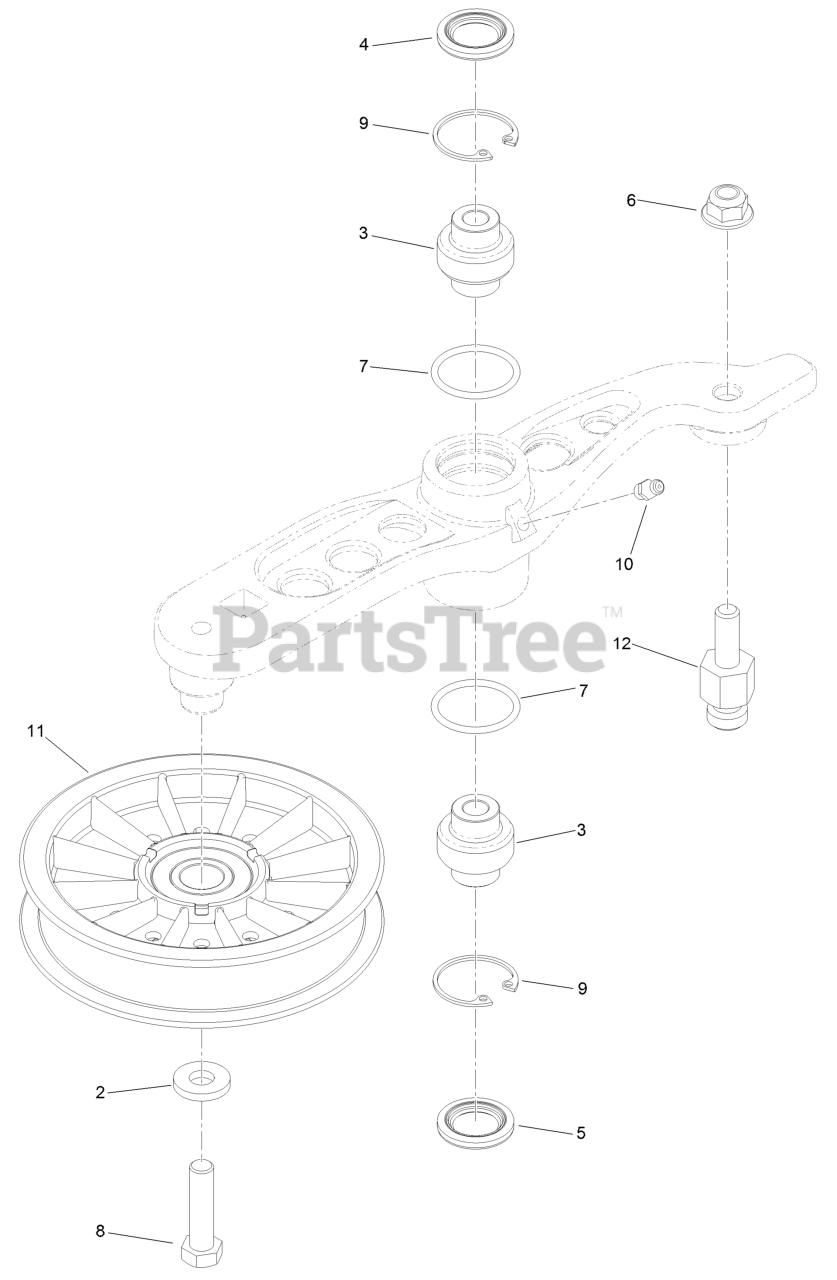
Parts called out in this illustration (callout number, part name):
3	Bearing-Spherical
4	Seal-Double Lip
5	Seal-Single Lip
6	Nut-Nyloc 3/8-16 Flg
8	Screw-HH 3/8-16 X 1 1/2
9	Ring-Retaining
10	Zerk-1/4-28 Str
11	Pulley-Idler
12	Pin-Spring Anchor
